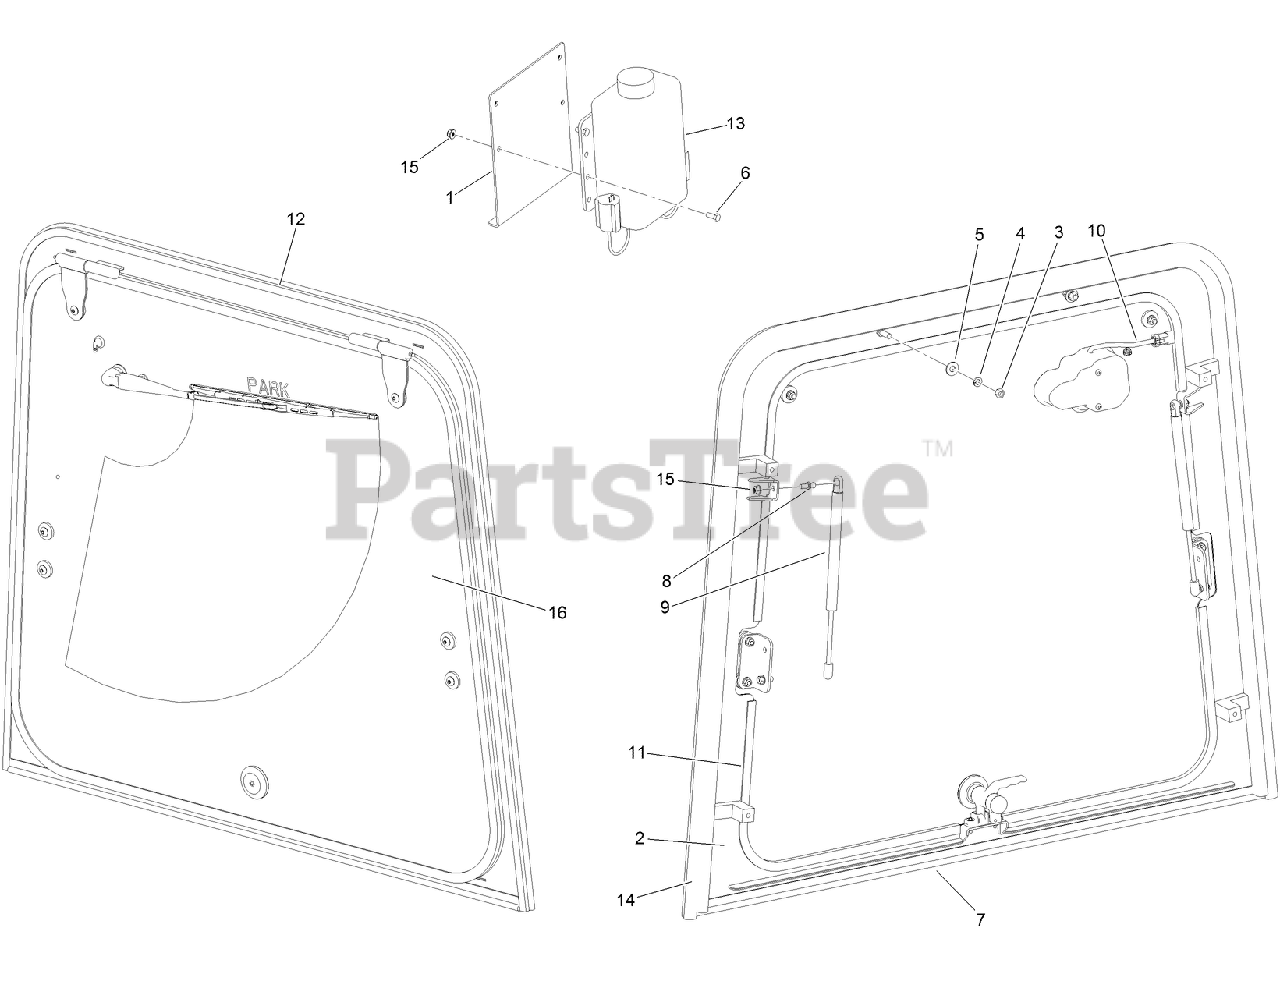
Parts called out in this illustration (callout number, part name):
1	MOUNT-PUMP, WASHER
2	PANEL-REAR
3	NUT-HEX
4	WASHER-LOCK
5	WASHER-FLAT
6	BOLT-HHCS
8	STUD-BALL, GAS SPRING
9	SPRING-GAS
10	HOSE-WASHER
11	SEAL-TRIM, MEDIUM
12	SEAL-RUBBER
13	WINDSHIELD WASHER KIT
14	SEAL-RUBBER
15	NUT-HEX
16	REAR WINDOW ASM
